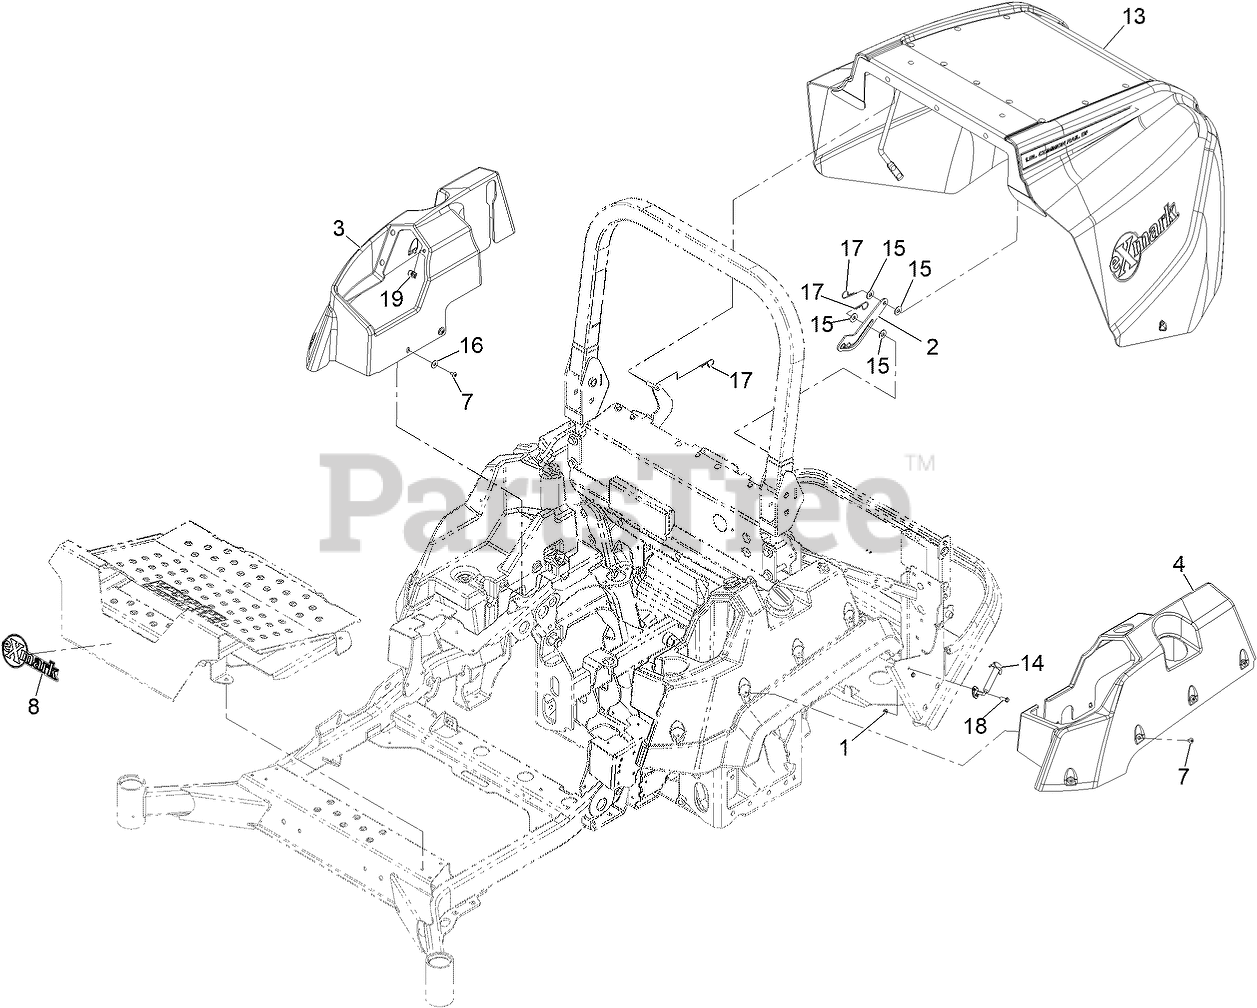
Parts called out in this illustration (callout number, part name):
2	PROP-HOOD
3	COVER-TANK, RH
4	COVER-TANK, LH
7	SCREW-TORX
8	DECAL-EXMARK
13	ASM, HOOD LZSD
14	LATCH-HOOK
15	WASHER-FLAT
16	WASHER-FLAT
17	PIN-COTTER, HAIR
18	SCREW-HWH
